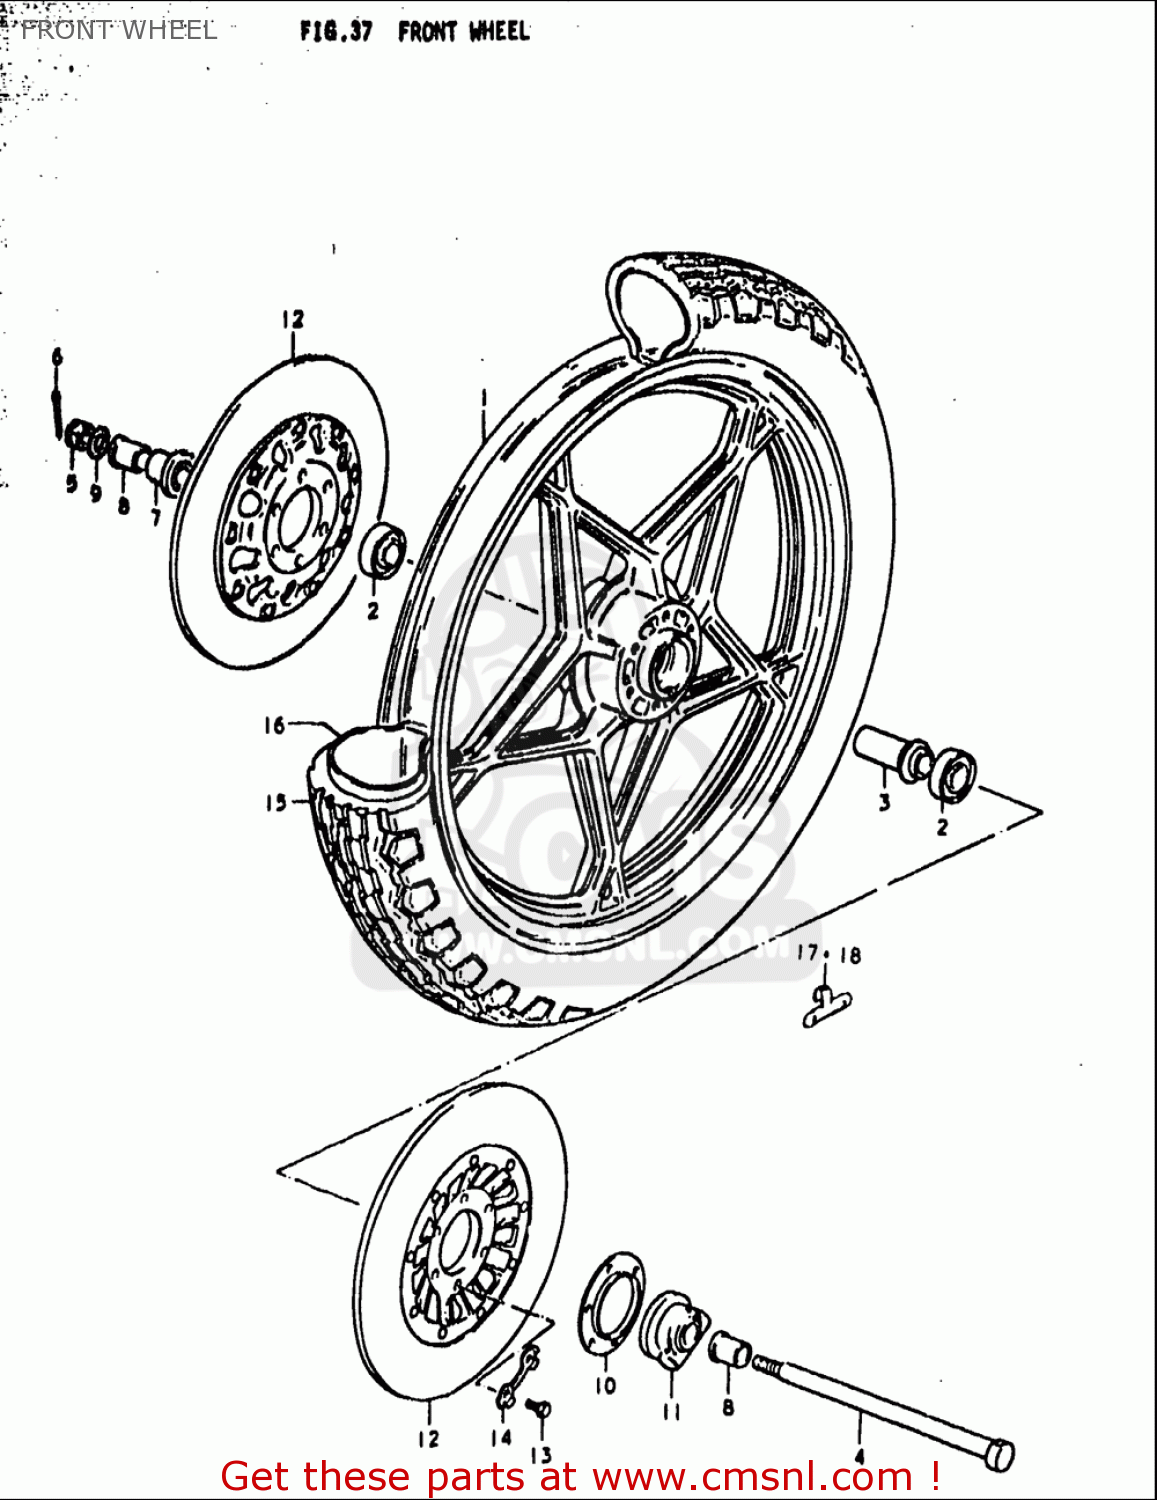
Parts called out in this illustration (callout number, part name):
1	WHEEL,FR(19XMT1.85)
2	B1 15X42X13 BEA
3	SPACER,FR HUB BEARING
4	AXLE,FR
5	NUT 12MM
6	PIN
7	SPACER,FR AXLE,R
8	SPACER,FR AXLE,L
9	WASHER
11	BOX ASSY,SPEEDOMETER GEAR
13	BOLT(8X30)
14	WASHER
16	TUBE ASSEMBLY,WHEEL,INNER
17	BALANCER,WHEEL
